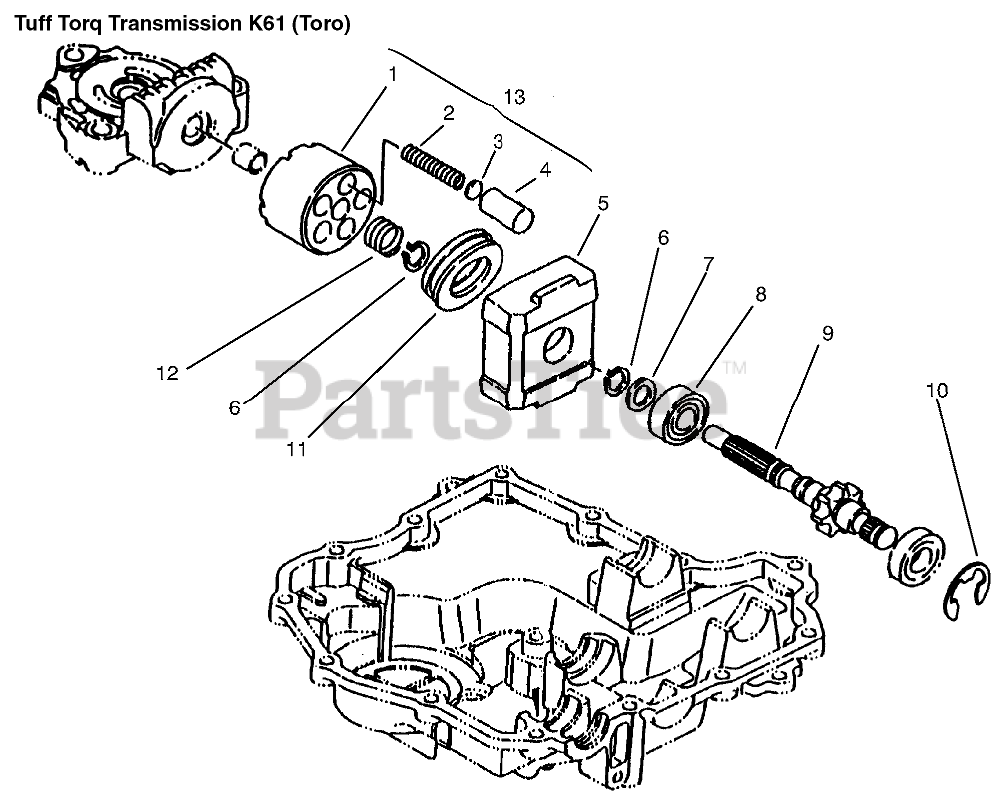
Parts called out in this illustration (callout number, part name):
1	Block-Cylinder
3	Washer
5	HOUSING
6	RING-SNAP
7	WASHER
8	BEARING-BALL
9	SHAFT - MOTOR
10	E-RING
11	BEARING-THRUST
13	ASM - CYCLINDER INC 6-9
